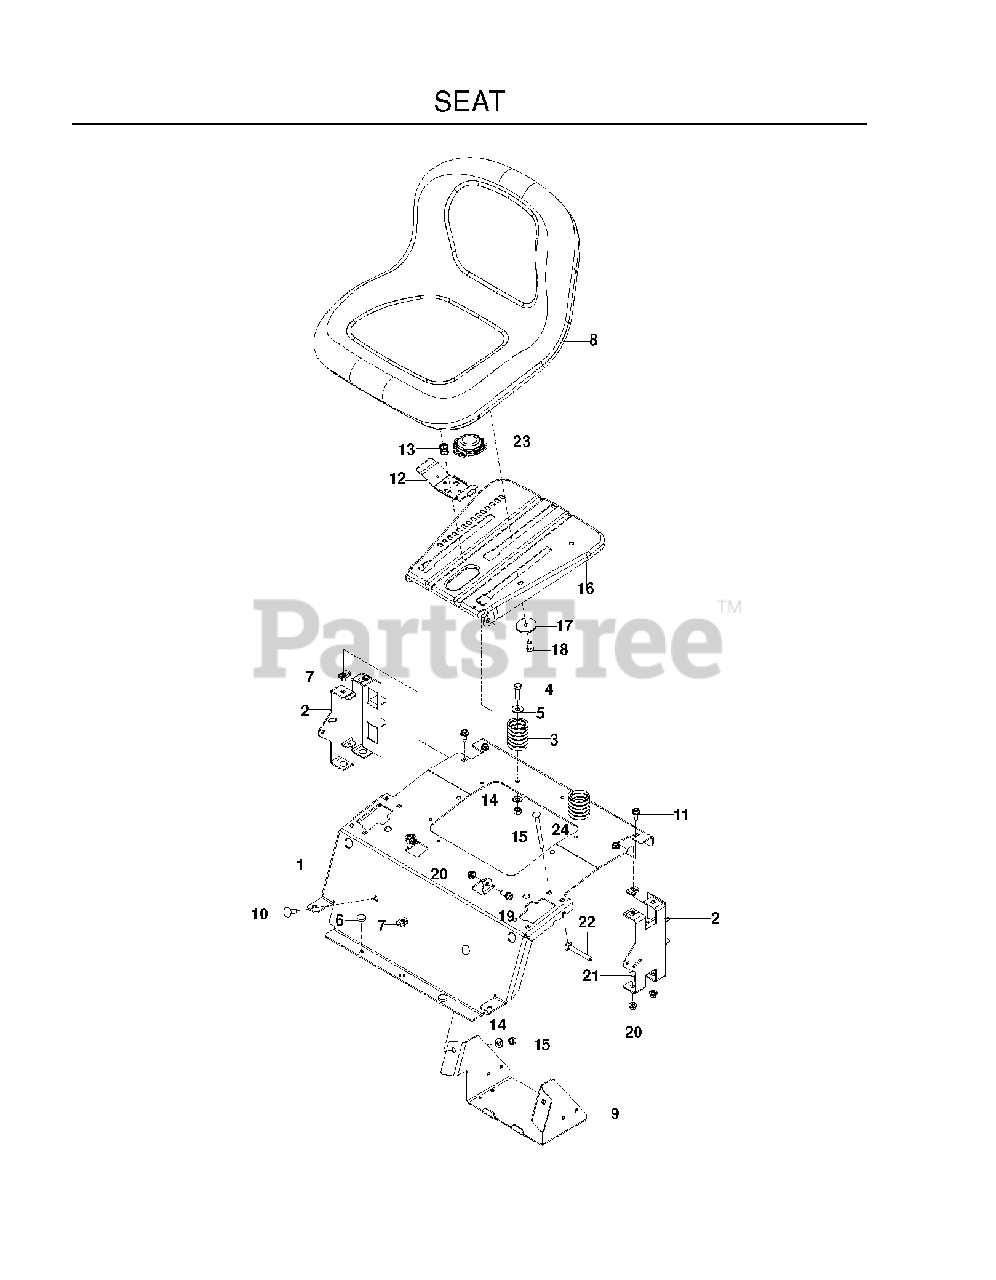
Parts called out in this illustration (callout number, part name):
1	SUPPORT, SEAT ORANGE
2	SUPPORT, REAR SEAT, BLACK
3	SPRING, SEAT
4	HCS 3/8C X 1 1/4 GR5
5	RP WASHER 3/8 FLAT
6	GROMMET, BUMPER
7	U-CLIP 5/16-18 NUT RETAINER
8	RP SEAT, TH150, GREY, MILSCO
9	BOX, BATTERY, BLACK
10	RHSNB 3/8C X 1
11	BOLT 5/16-18 X 3/4
12	HANDLE.SLIDE.SEAT.TEX.BLACK
13	SPRING.LATCH.SEAT.TEX
14	WASHER 3/8 SAE FLAT
15	NUT 3/8-16 NYLOC
16	PAN.ASM.SEAT.3PT
17	WASHER, 3/8 SPEC
18	HCS 3/8-16 X 5/8 GR 5 ZD
19	BOLT, SHOULDER
20	5/16-18 NYLOC FLANGE NUT
21	BOLT 5/16C X 3/4" CARRIAGE
22	RHSNB 5/16-18 X 2-1/2 GR5 ZD
23	SWITCH, SEAT N/C
24	RHSNB 5/16-18 X 4 GR 5 ZD
